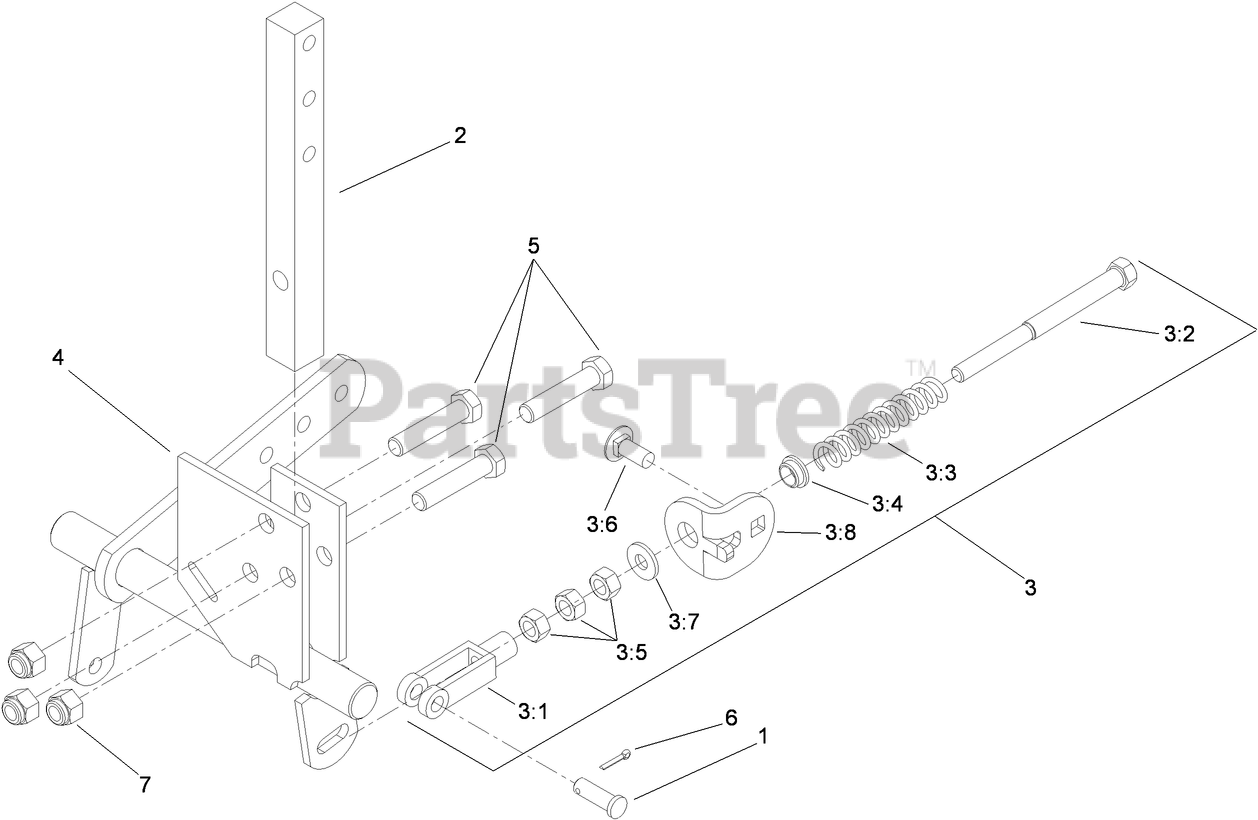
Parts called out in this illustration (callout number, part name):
1	PIN-CLEVIS
2	ARM-SHAFT, CONTROL
3	NEUTRAL RETURN ASM
3:1	YOKE-ADJUSTABLE
3:2	BOLT-RETURN, NEUTRAL
3:3	SPRING-RETURN, NEUTRAL
3:4	BUSHING-NYLON, FLANGED
3:5	NUT-HEX
3:6	SCREW-CARR
3:7	WASHER-FLAT
3:8	TAB-ADJUSTMENT
4	CONTROL-MOTION, LH
5	SCREW-HH
6	PIN-COTTER
7	NUT-LOCK, NI
